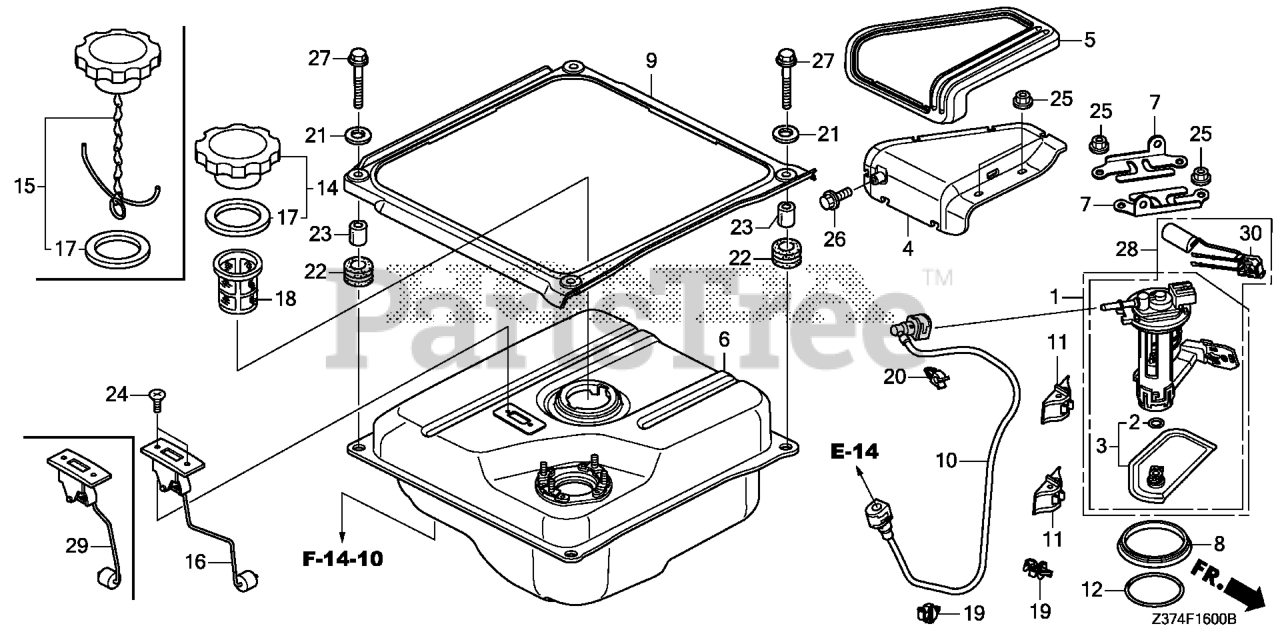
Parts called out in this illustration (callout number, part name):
1	PUMP UNIT, FUEL (MSDS)
2	O-RING (6.8X1.9)
3	FILTER SET
4	COVER, FUEL PUMP *NH700M* (ALABASTER SILVER METALLIC)
5	SEAL, FUEL PUMP COVER
6	TANK, FUEL *R280* (POWER RED)
6	TANK, FUEL *R280* (COO) (POWER RED)
7	RETAINER, FUEL PUMP
9	SEAL, FUEL TANK
10	HOSE, FUEL FEED
11	GROMMET, FUEL FEED
12	O-RING, FUEL PUMP
15	CAP, FUEL FILLER
16	METER ASSY., FUEL (NOT AVAILABLE)
16	METER ASSY., FUEL
17	GASKET, FUEL FILLER CAP
18	FILTER, FUEL
19	CLIP, THROTTLE WIRE
20	CLIP, RETURN PIPE (6MM) (NOT AVAILABLE)
21	WASHER (6MM)
22	RUBBER, TANK CUSHION
23	COLLAR, TANK CUSHION
24	SCREW, FLAT (5X10)
25	NUT, FLANGE (6MM)
26	BOLT, FLANGE (6X12)
27	BOLT, FLANGE (6X25)
